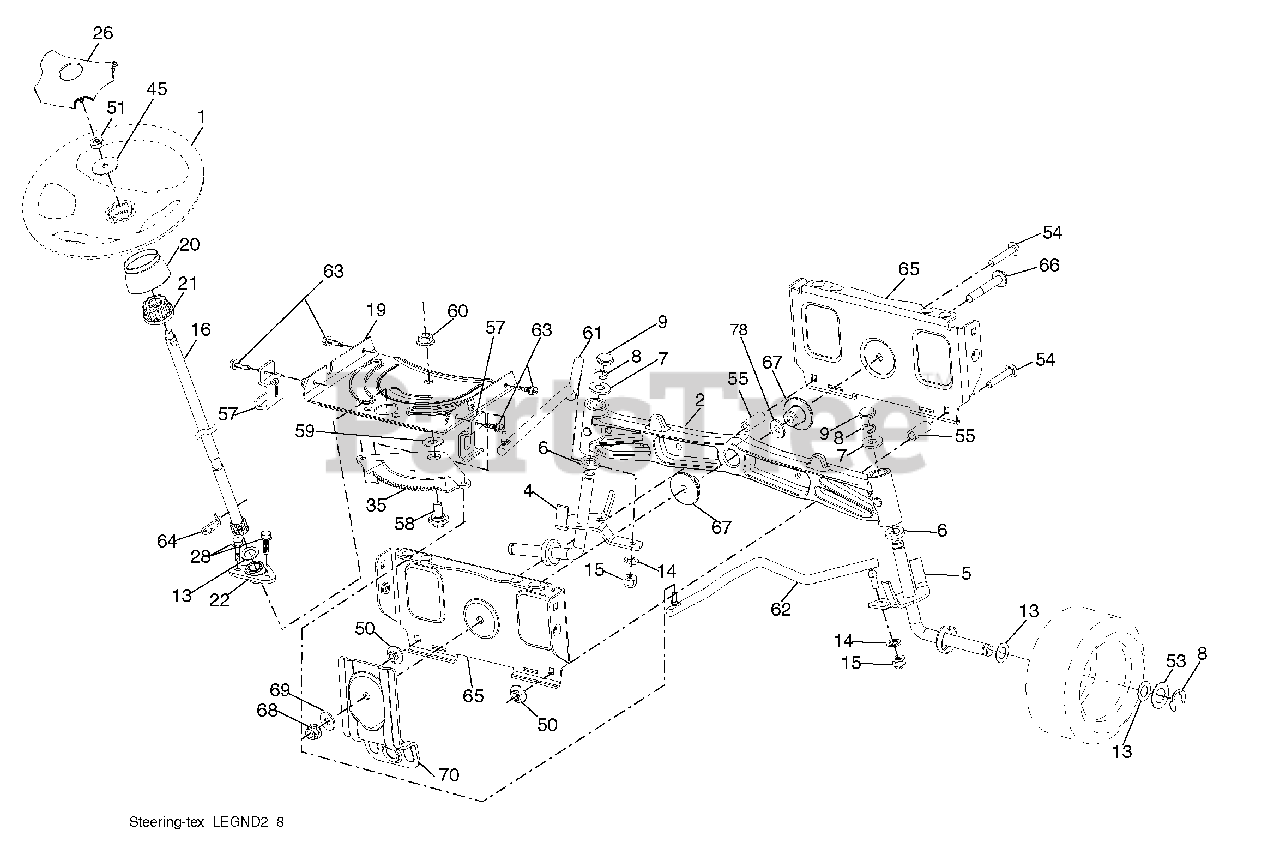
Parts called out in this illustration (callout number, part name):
1	Wheel, Steering
2	Axle Asm., Front
4	Spindle Asm., LH
5	Spindle Asm., RH
6	Bearing, Race Thrust Harden
7	Washer 25/32 x 1-5/8 x 16 Ga.
8	Ring, Clip #T5304-75
9	Cap, Spindle
13	Washer 25/32 x 1-1/4 x 16 Ga.
14	Washer, Lock Hvy Hlcl Spr 3/8
15	Nut, Crown Lock 3/8-24 unf
16	Shaft Steering
19	Plate Steering
20	Boot, Steering
21	Adapter, Wheel Steering
22	Bushing, Strg. Blk
26	Insert, Wheel Steering
28	Screw 3/8-16 x 3/4
35	Gear, Sector Plate
45	Washer 9/16 ID x 2-3/8 x 12 Ga.
50	Nut Lock 3/8-16 unc
51	Nut Hex Jam Toplock 1/2-20 unf
53	Washer Hardened .793 x 1.637 x .060
54	Bolt Hex 3/8-16 unc x 2-1/4
55	Spacer Brace Axle
57	Bracket Upstop
58	Bolt Shoulder Sector Pivot CFM
59	Washer Thrust Sector Steering
60	Nut Flange Lock 5/8-11
61	Draglink, LH
62	Draglink, RH
63	Screw 5/16-18 x 3/4
64	Retainer Clip Spring Steering
65	Brace Axle Front
66	Bolt Hex Fghd 7/16-14 x 3 Serr
67	Bushing PM Front Axle
68	Nut Lock Flange 7/16-14 Gr. 5
69	Washer 1.5 x .505 x .118
70	Bracket Deck Susp. Front
78	Washer Thrust .515 x .750 x .033
